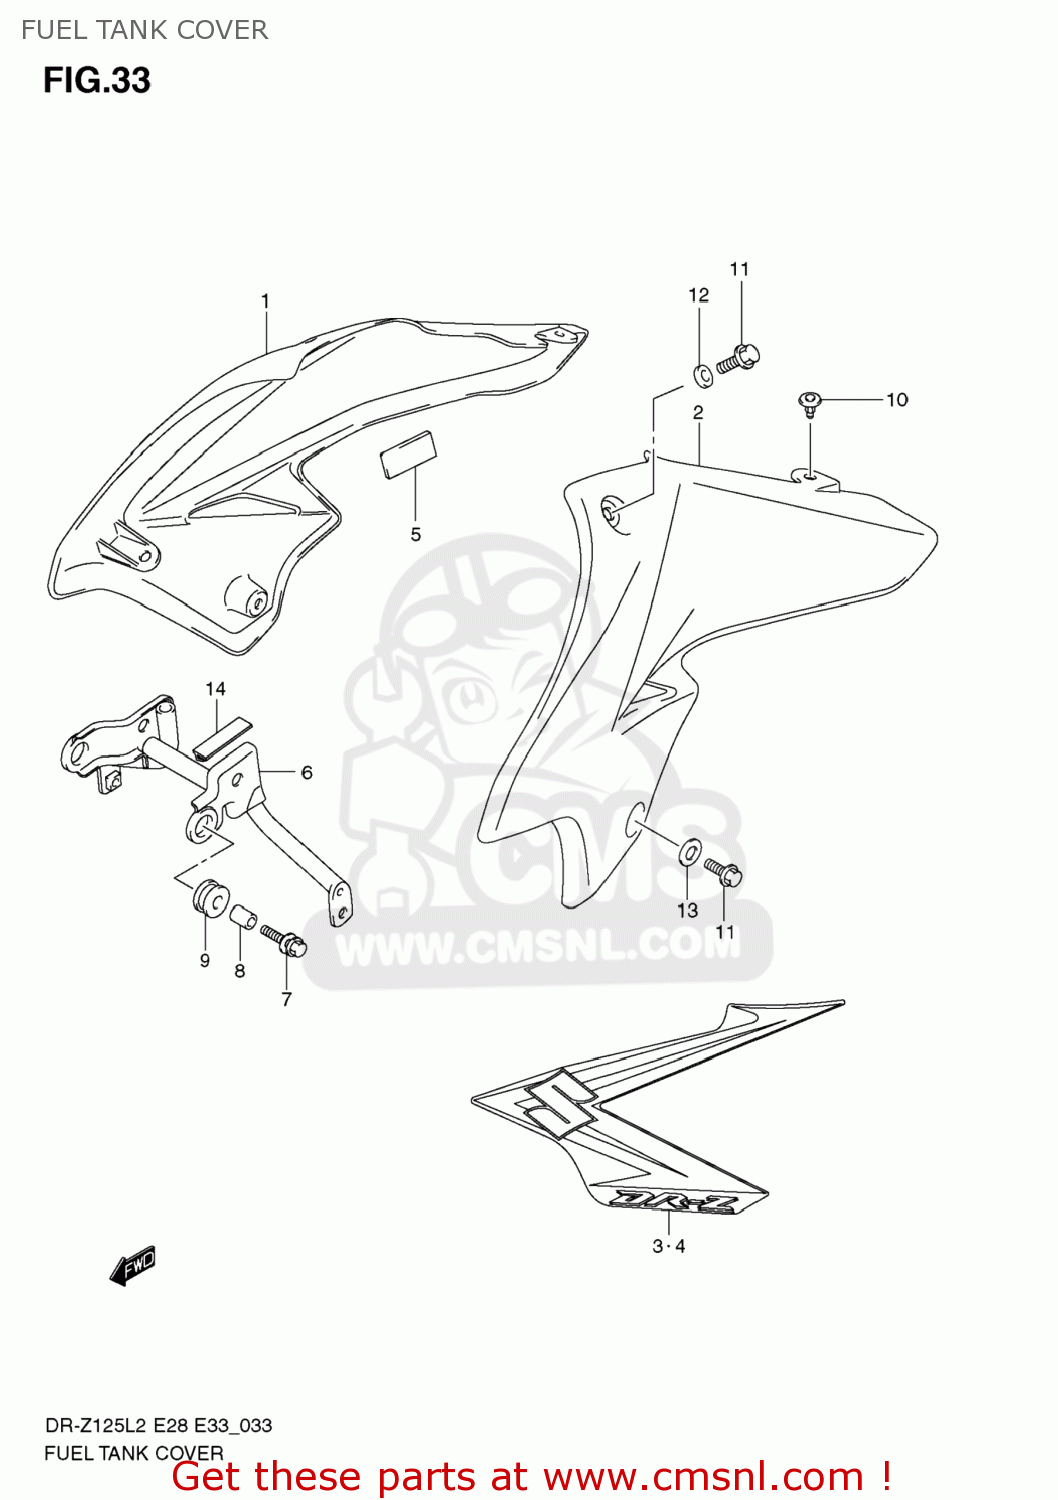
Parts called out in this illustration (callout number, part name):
1	COVER,FUEL TANK,R
2	COVER,FUEL TANK,L
3	TAPE SET,FUEL TANK COVER,R
4	TAPE SET,FUEL TANK COVER,L
5	CUSHION,FUEL TANK COVER
6	BRACKET,FUEL TANK FR
7	BOLT(6X25)
8	SPACER(6.5X9X13.5)
9	CUSHION,FUEL TANK SIDE
10	CLIP(BLACK)
11	BOLT
12	WASHER
13	WASHER
14	MOLDING
